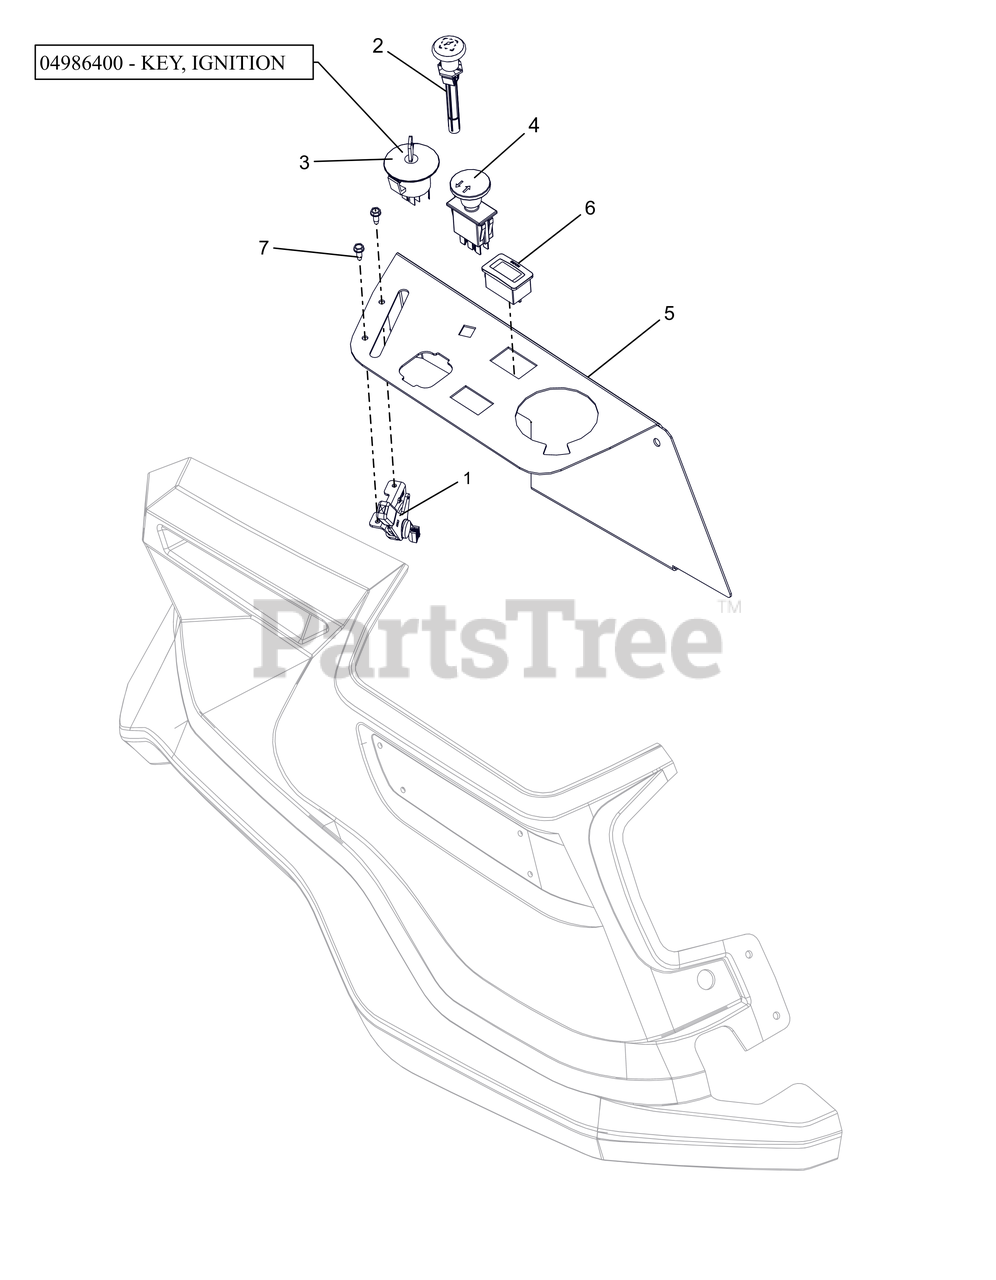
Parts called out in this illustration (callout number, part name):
1	CABLE - THROTTLE CONTROL
2	CABLE - CHOKE, SNAP-IN
3	KEYSWITCH-IGNITION 4 POS
3	KEY, IGNITION
4	SWITCH, CLUTCH (YELLOW)
5	PANEL, RIGHT SIDE FENDER MOUNT
6	HOUR METER
7	SCR,TAP #10-24X.50 HWH TR ZCC
